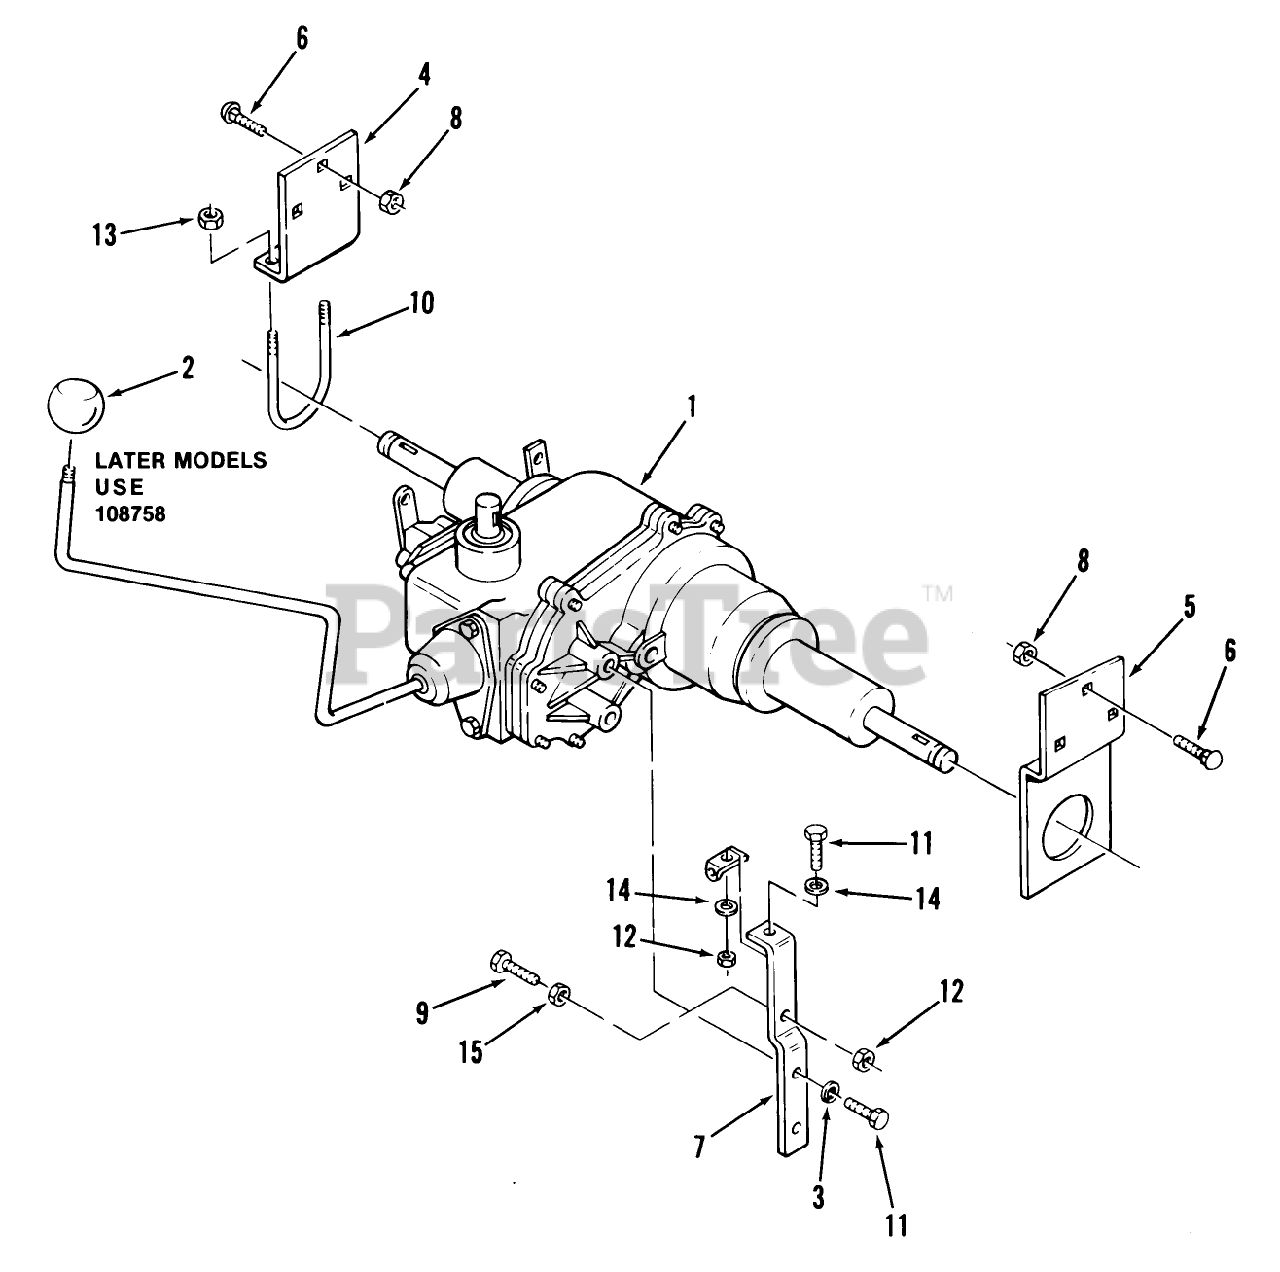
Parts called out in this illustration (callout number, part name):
1	ORDER FROM PEERLESS
2	SHIFT KNOB
6	CARRIAGE BOLT -4
14	WASHER 5/16 SAE
